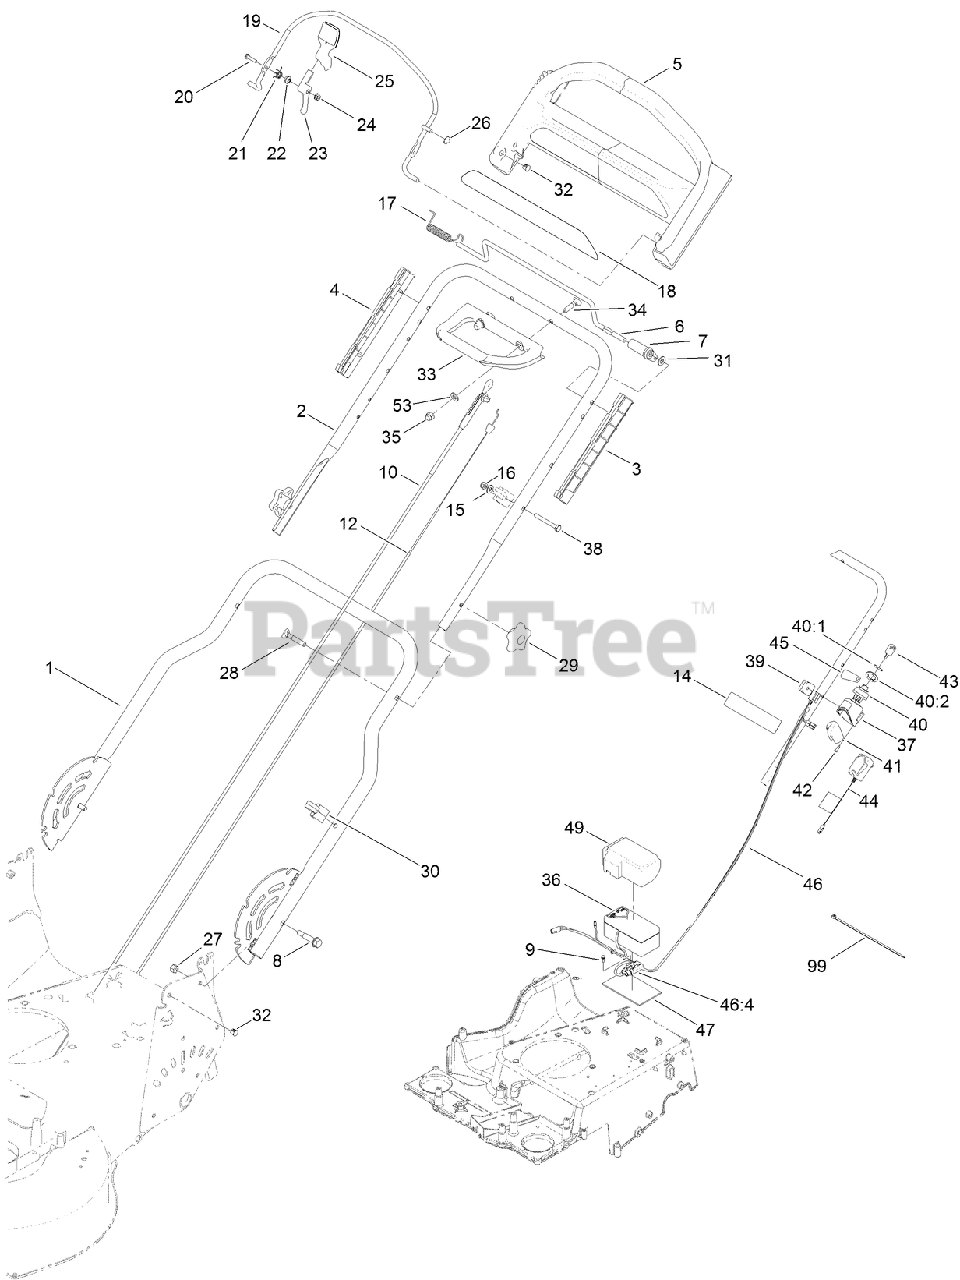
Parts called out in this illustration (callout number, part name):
1	HANDLE-LOWER
2	HANDLE-UPPER
3	GUIDE-LH
4	GUIDE-RH
5	HANDLE-CONTROL
7	LEVER-TRACTION
8	BOLT-SHOULDER, HHF
9	SCREW-TAPTITE
12	CABLE-TRACTION
14	DECAL-WARNING
15	WASHER-FLAT
16	NUT-LOCK, NI
18	DECAL-HANDLE
19	BAIL-BRAKE
20	SCREW-HWH
21	SPRING-TORSION
22	SPACER
23	LEVER
24	NUT-LOCK, FLANGE
26	NUT-SPEED
27	NUT-LOCK, NI
28	SCREW-HANDLE
29	KNOB-HANDLE
30	GUIDE-CABLE
31	WASHER-PLAIN
32	PLUG-DOME
33	HANDLE-ASSIST, TRACTION
34	SCREW-HANDLE
35	NUT-HEX, NYLON CAP
36	BATTERY-WET
37	HOUSING-SWITCH, KEY
38	SCREW-HH
39	ANCHOR-CABLE, UPPER
40	SWITCH-STARTER
40:1	NUT-HH
40:2	WASHER-LOCK
41	COVER-SWTCH
42	SCREW-PPH
45	DECAL-SWITCH, IGNITION
46	HARNESS-WIRE
46:4	FUSE-40 AMP
47	FOAM-BATTERY
49	COVER-BATTERY
53	SPACER
99	TIE-CABLE
